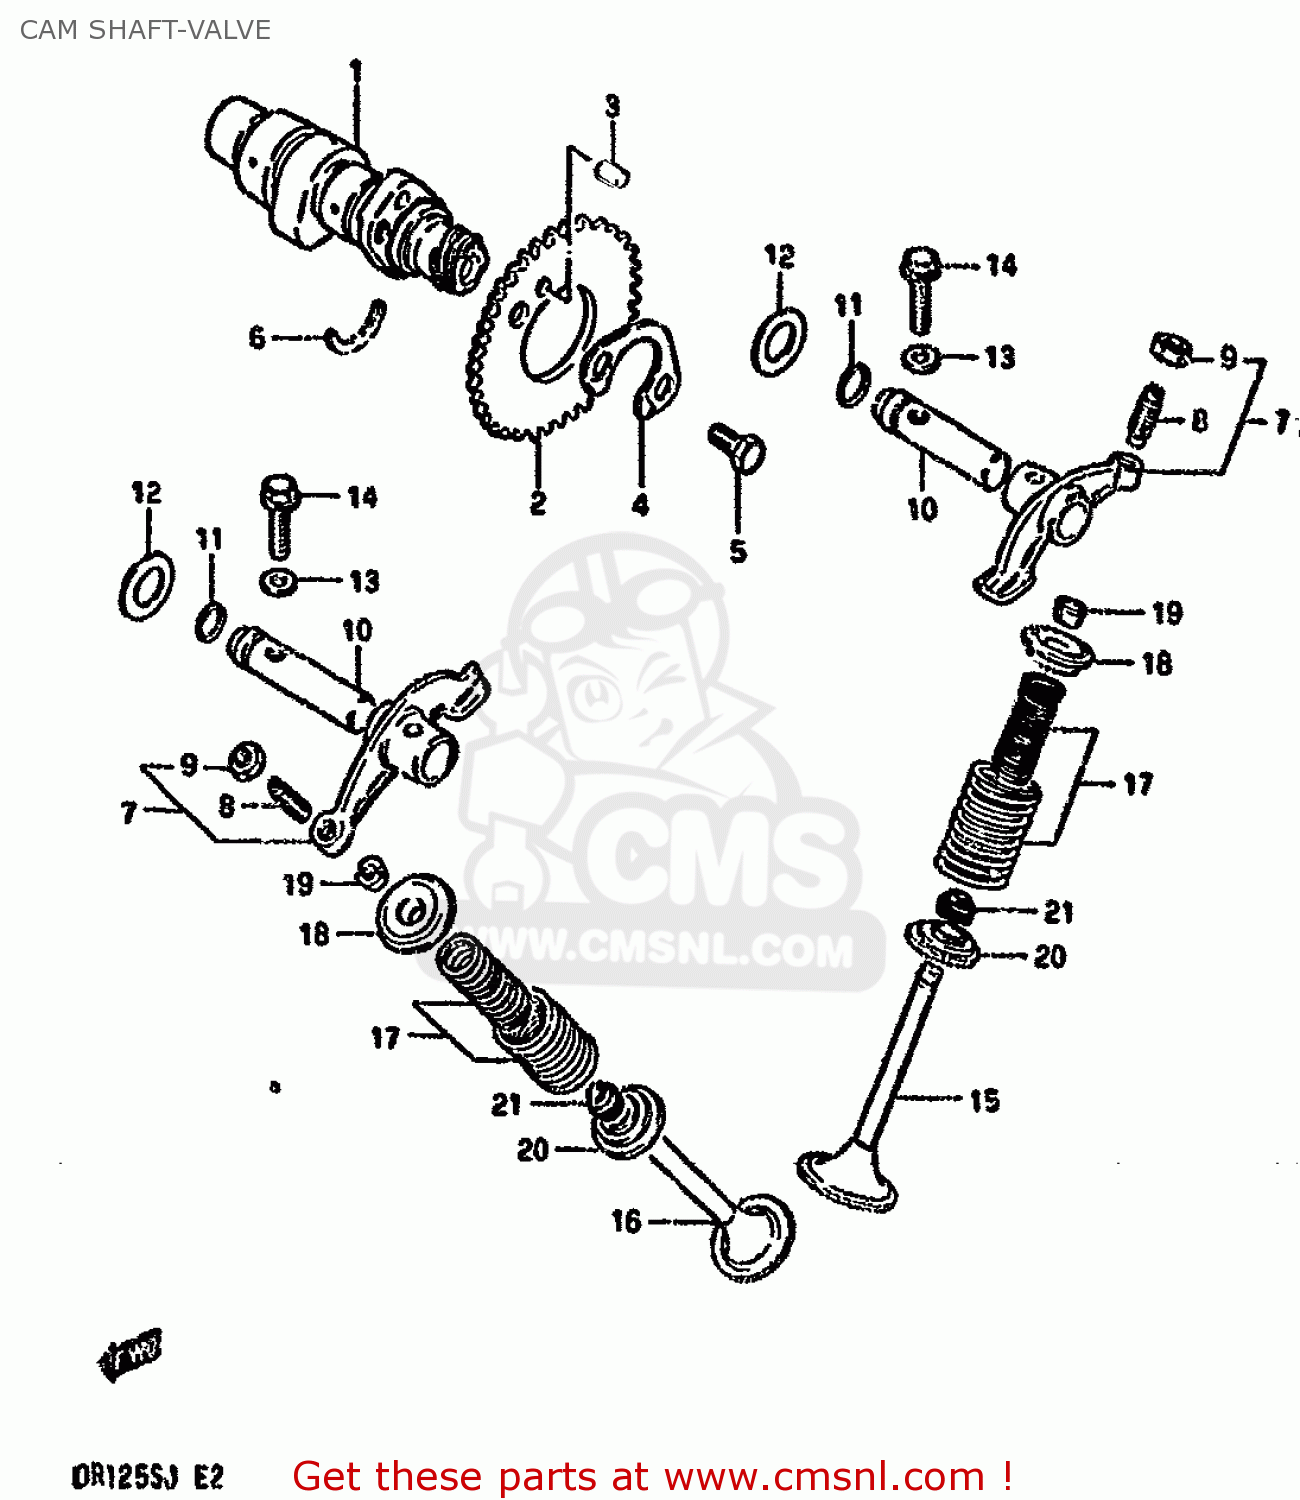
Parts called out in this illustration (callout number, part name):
1	CAMSHAFT
2	SPROCKET,CAMSHAFT
3	PIN(5X8)
4	WASHER,SPROCKET
5	BOLT(6X10.5)
6	C RING
7	ARM,VALVE ROCKER
8	SCREW,TAPPET ADJUSTING
9	NUT,ADJUSTING SCREW
10	SHAFT,VALVE ROCKET
11	O RING(D:1.9,ID:8.6)
12	WASHER
13	GASKET(5.8X13X1.2) (NAS)
14	BOLT
15	VALVE,INTAKE
16	VALVE,EXHAUST
17	SPRING SET,VALVE
18	RETAINER,VALVE SPRING
19	COTTER,VALVE
20	SEAT,VALVE SPRING
21	OIL SEAL
